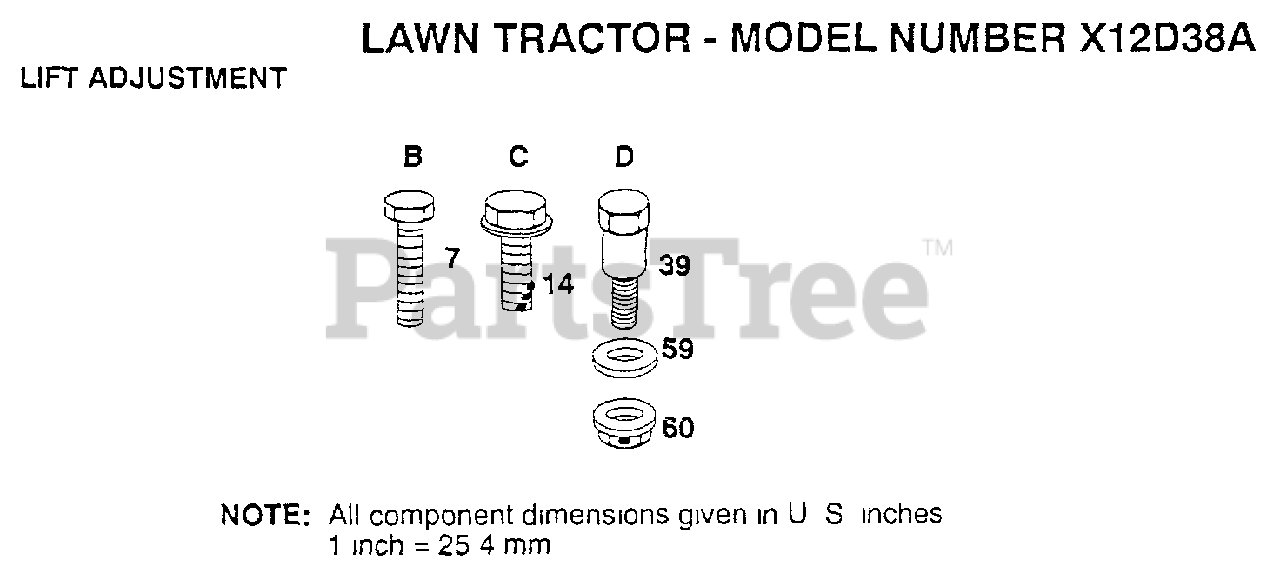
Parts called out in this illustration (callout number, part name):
7	SCREW
14	SCREW HEX CRT
39	"BOLT, SHOULDER LT"
59	WASHER T
60	NUT SPECIAL T
